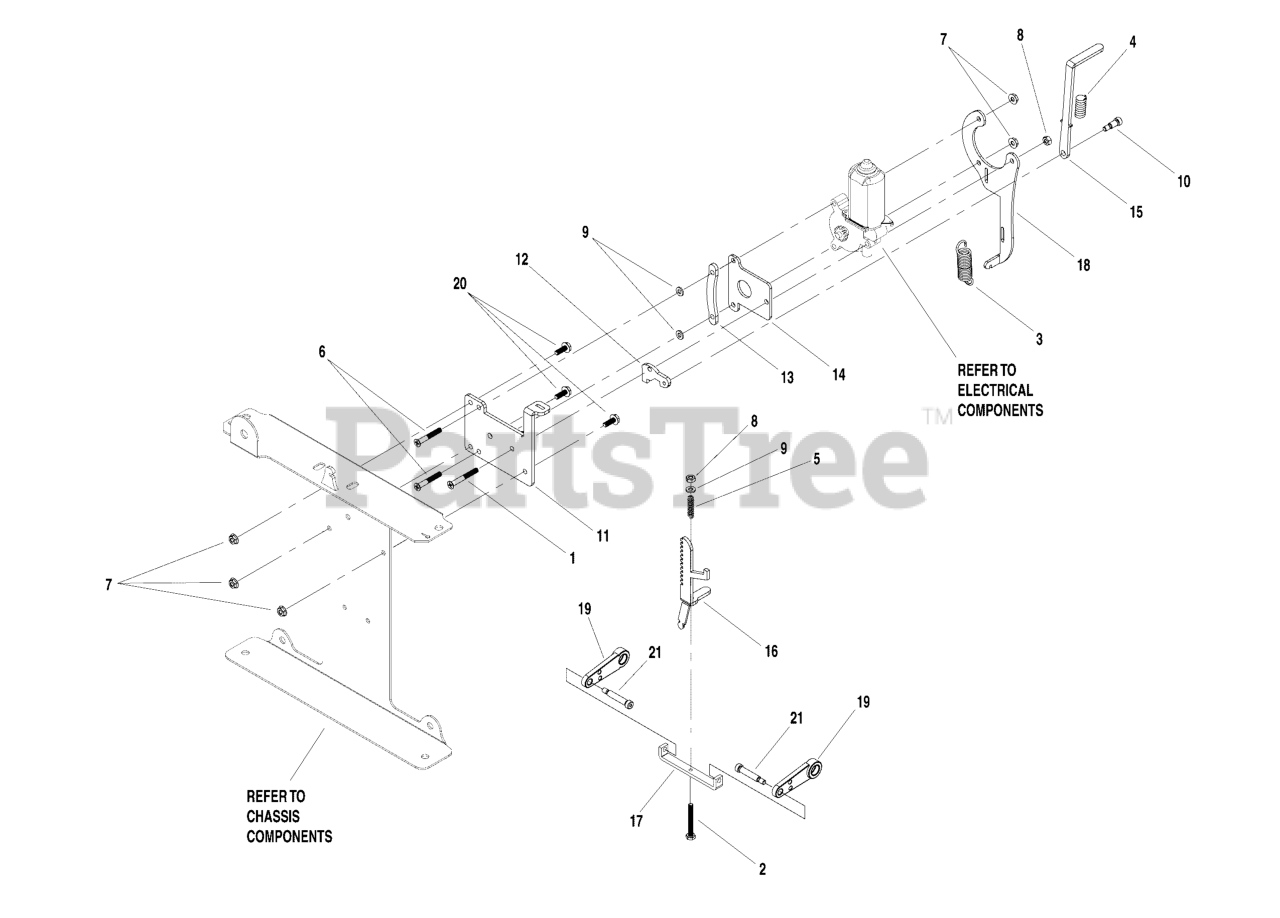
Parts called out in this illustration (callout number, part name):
1	SCREW, 1/4-20 X 2, PHLPS, SS
2	BOLT, 1/4-20 X 2", GD5
3	SPRING, EXTENSION, #29
4	SPRING, COMPRESSION, #29
5	SPRING, COMPRESSION, #21
6	SCREW, 1/4-20 X 1-3/4, ALLEN, SS
7	NUT, 1/4-20 HEX SERR. FLANGE
8	NUT, 1/4-20 HEX NYLON LOCK
9	WASHER, 1/4 SAE, CZ
10	BOLT, 5/16 X 1/2, SHLDR, SS
11	PLATE, BRAKE BACKING (X3-1511)
12	PLATE, BRAKE CAM, CZ
13	PLATE, BRAKE SPACER - BLK
14	PLATE, CAM COVER (X3-1514)
15	PLATE, BRAKE RELEASE LEVER,CZ
16	WELD, BRAKE GEAR RACK,CZ
17	ARM, Lever
18	PLATE, SWITCH MOUNT, CZ
19	Refer to: Hydraulic and Control Lever Group
20	BOLT, 1/4-20 X 3/4, FLANGE, CZ
21	BOLT, 5/16 X 1-1/4, SHLDR, SS
